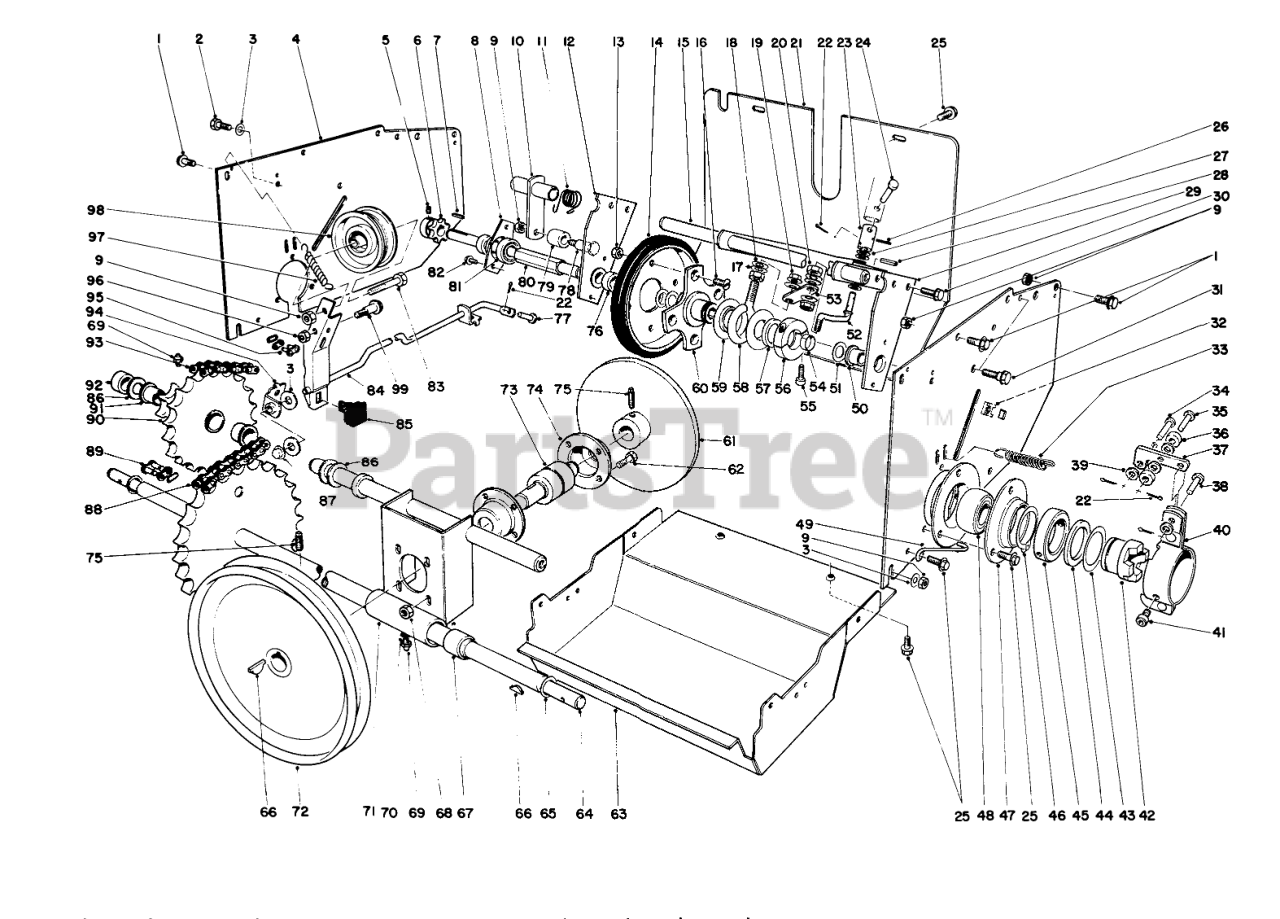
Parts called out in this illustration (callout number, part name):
1	SCREW-HH
2	SCREW-HHFTF
3	WASHER-FLAT
4	Side Plate Drive
5	SCREW-HSH
6	SPROCKET
8	BEARING CUP
9	NUT-LOCK, NI
10	CHAIN TENSION ARM WA
11	TORSION SPRING
12	HEX SHAFT MOUNT R
13	NUT-LOCK, NI
14	FRICTION WHEEL
15	Bracket Dead Shaft
16	5/16-18X5/8 FLT HD MS
17	WASHER-FLAT
18	WASHER-SPRING
19	NUT-LOCK, FLANGE
20	NUT-LOCK
21	REAR COVER R
22	PIN-COTTER
23	U JOINT TUBE
24	CLEVIS PIN
25	SCREW-HWH
26	PIN-SPRING
27	Clevis Pin
28	PIN-ROLL
29	Hex Shaft Mounting (Incl . Ref #50)
30	SCREW-HWHTF
31	SHOULDER SCREW
32	RETAINER NUT
33	EXTENSION SPRING
34	PIN-CLEVIS
35	PIN-CLEVIS
36	CLUTCH ROLLER
37	CLUTCH CAM ARM
38	PIN-CLEVIS
39	WASHER-FLAT
40	CLUTCH MT BRKT ASM
41	SCREW-HSH
42	WHEEL CLUTCH
43	THRUST WASHER
44	THRUST BEARING
45	CLUTCH MOUNT COLLAR
46	RING-RETAINING, EXTERNAL
47	BEARING FLANGE
48	BEARING
49	CLUTCH RETAINER
50	BUSHING
51	WASHER-FLAT
52	CONNECTION ROD
53	SHIFT ROD PIVOT
54	SPLIT SPACER
55	SCREW-HSH
56	ColIar
57	WASHER-THRUST
58	SLIDER RING COLLAR
59	SLIDER RING
60	TRACTION DISC HUB
61	FRICTION PLATE O
62	SCREW-HH
63	LOWER SHIELD R
64	AXLE SHAFT WA
65	WASHER
66	KEY-WOODRUFF
67	Bearing
68	NUT-KEPS
69	FITTING-GREASE
70	WASHER-LOCK
71	Bulkhead (Incl. Ref. #67)
72	Pulley
73	Friction Plate Shaft
74	HOUSING BEARING
75	Set Screw
76	SPACER
77	PIN-CLEVIS
78	SHOULDER BOLT
79	CHAIN TENSION ROLLER
80	FRICTION WHEEL SHAFT
81	BEARING
82	SCREW
83	SCREW-HH
84	Auger Brake Assembly (Incl . Ref . #85)
85	Brake Pad
86	WASHER-THRUST
87	PUSH NUT
88	Lower Chain (Incl. Ref. #89)
89	LINK-CHAIN
90	Sprocket (Incl. Ref. #69 & 91)
91	3/4ID X 3/4LG BSHG
92	SPACER-IDLER
93	UpperChain (Incl. Ref. #95)
94	Bracket-Clutch
95	LINK-CONNECTING
96	NUT-LOCK, CONE
97	SPRING
98	PULLEY-IDLER
99	BOLT-SHOULDER
